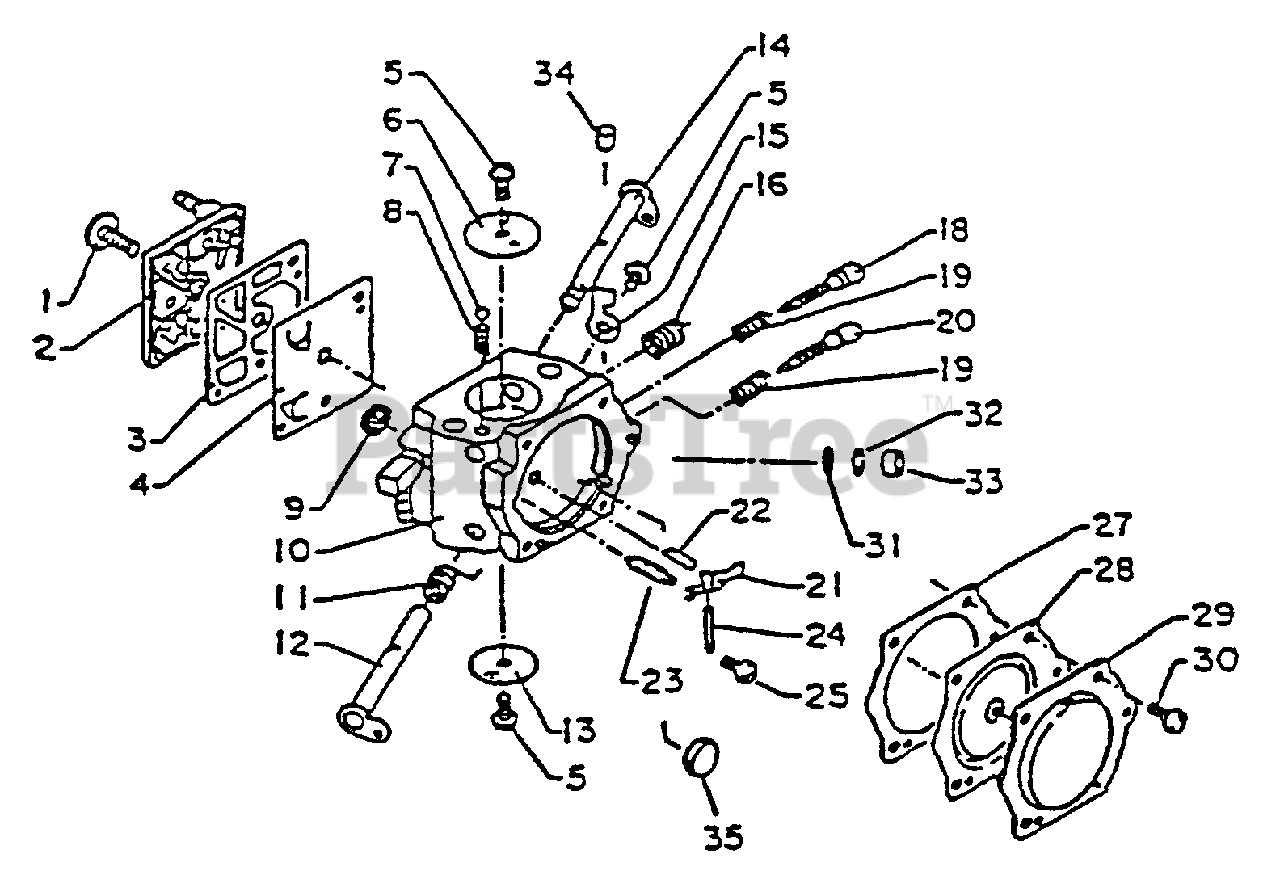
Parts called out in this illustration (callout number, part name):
2	COVER, FUEL PUMP
3	GASKET, PUMP
4	DIAPHRAGM, PUMP
6	VALVE, CHOKE
7	BALL, CHOKE FRICTION
9	STRAINER
10	BODY, CARBURETOR
11	SPRING, THROTTLE RETURN
12	SHAFT, THROTTLE
13	VALVE, THROTTLE
14	SHAFT, CHOKE
15	STOP, THROTTLE
16	SPRING, NEEDLE
18	NEEDLE, IDLE
19	SPRING, NEEDLE
20	NEEDLE, HIGH SPEED
21	LEVER, METERING
22	SPRING, METERING LEVER
23	VALVE, INLET NEEDLE
24	PIN, METERING LEVER
25	SCREW
27	GASKET, METERING
28	DIAPHRAGM, METERING
29	COVER, METERING DIAPHRAGM
30	SCREW
31	STRAINER
32	RING, RETAINING
33	PLUG, WELCH
34	PLUG, FRICTION
35	PLUG, WELCH
